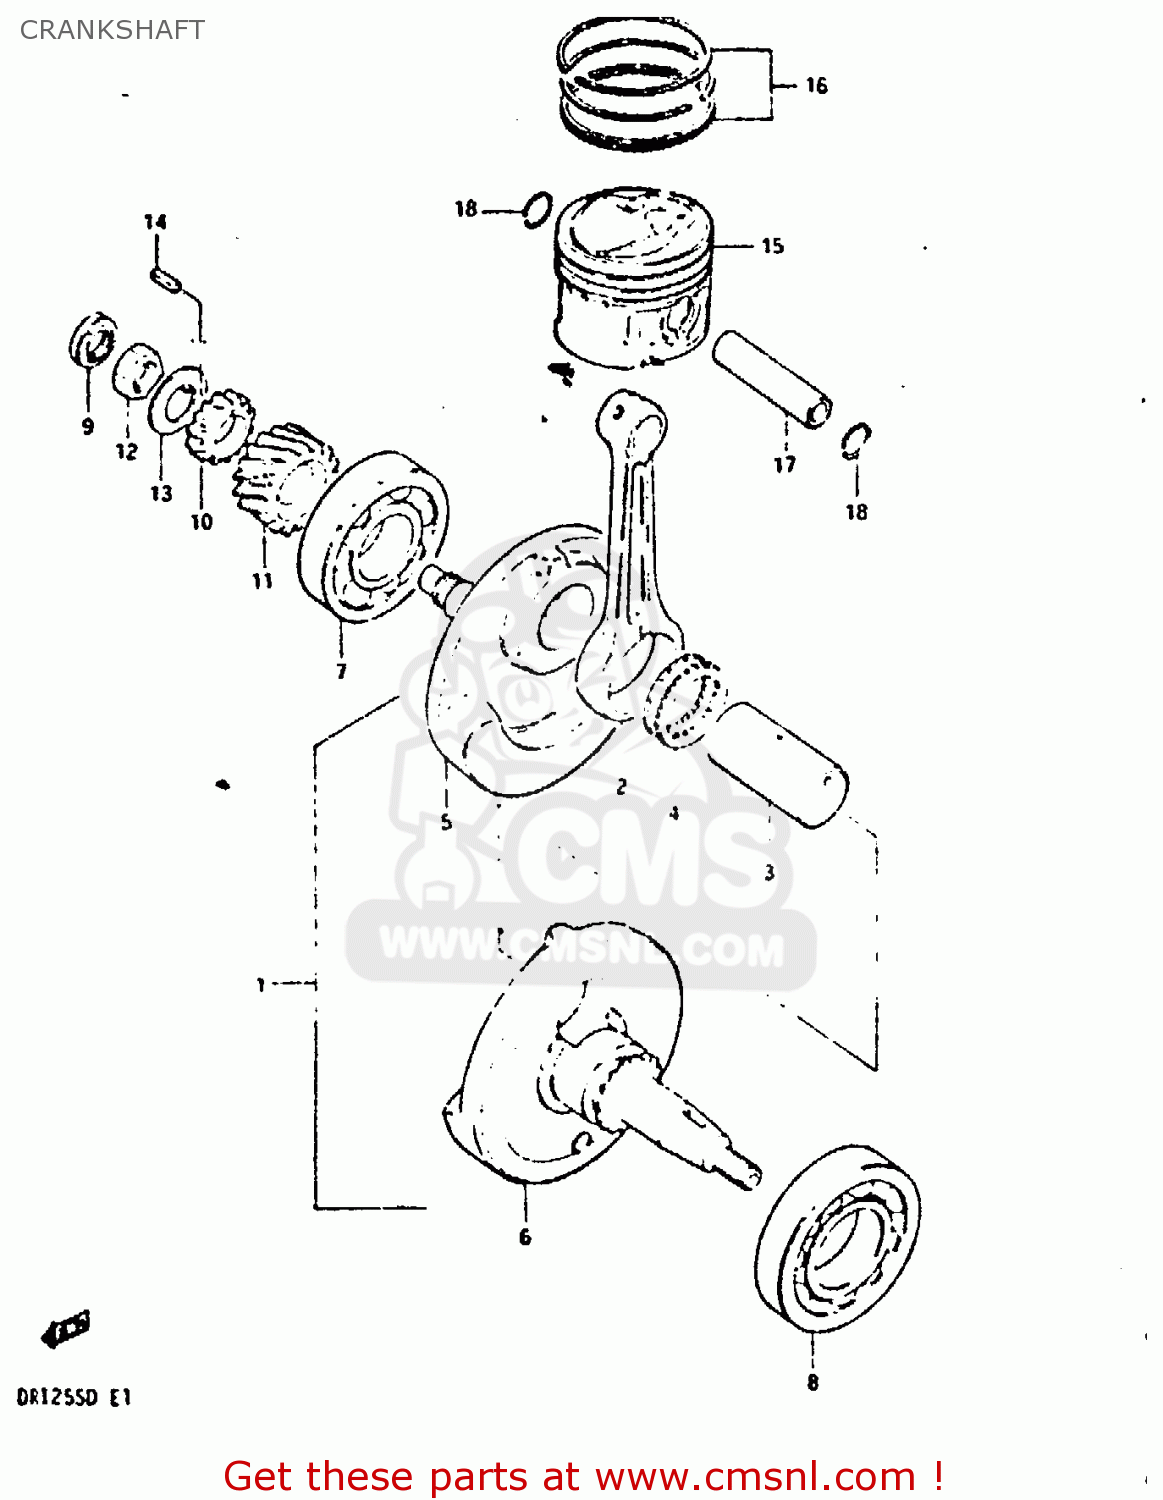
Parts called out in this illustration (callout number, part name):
1	CRANKSHAFT ASSEMBLY
2	CONNECTING ROD
3	PIN,CRANK
4	BEARING
5	CRANKSHAFT
6	CRANKSHAFT,LEFT
7	BEARING,MIDDLE
8	BEARING,LEFT
9	OIL SEAL
10	GEAR,OIL PUMP DRIVE
11	GEAR,PRIMARY DRIVE
12	NUT
13	WASHER
14	KEY
15	PISTON (STD)
16	RING SET,PISTON
17	PIN,PISTON
18	RING,SNAP 14MM
